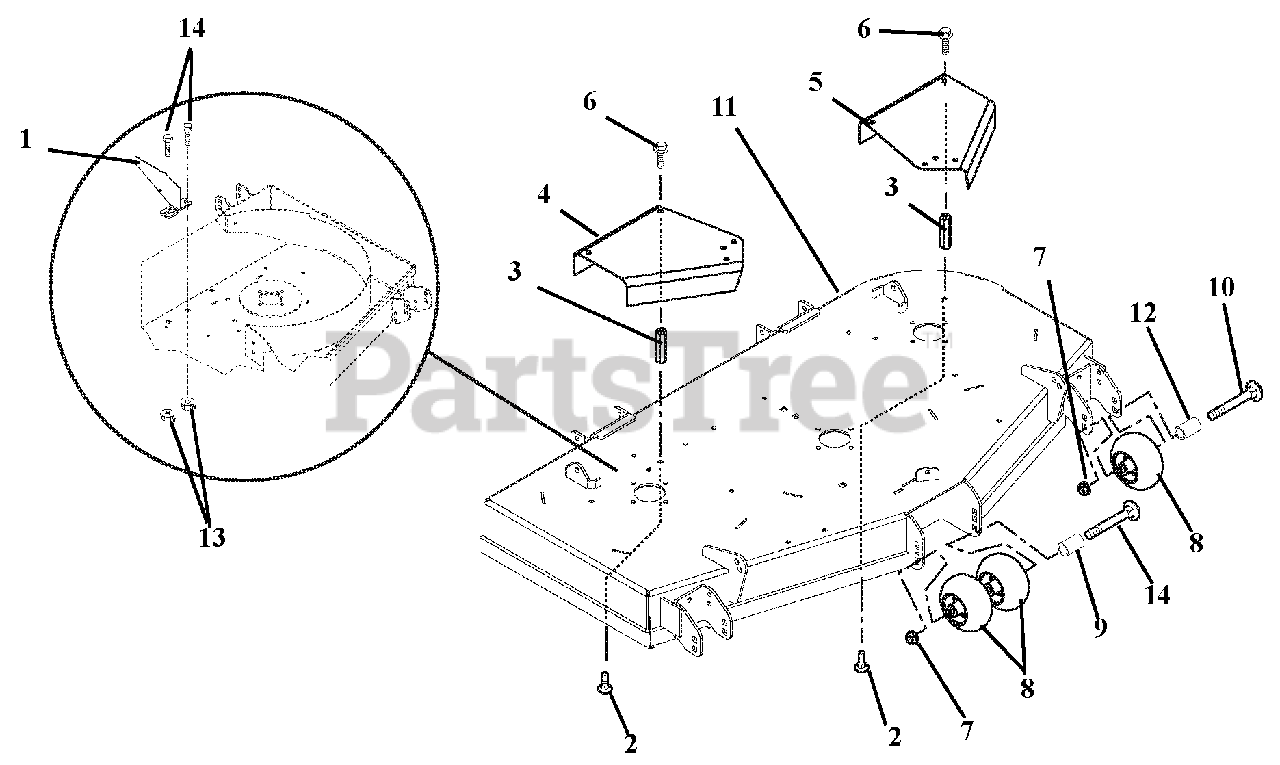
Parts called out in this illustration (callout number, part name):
1	Rear Deflector Baffle
2	Bolt, Round Head Square Neck .31-18 x .75 Loctite with Epoxy Patch
3	Nut, Coupling .31-18 x 3.00
4	52-in. Right Hand Spindle Guard (992322)
5	52-in. Left Hand Spindle Guard(992322)
6	Bolt, SEMS .31-18 x .62
7	Nut .50-13 Nyloc Flange
8	Anti-Scalp Wheel
10	Bolt-Round Head Square Neck .50-13 x 5.00
11	52-in. Mower Deck (992322)
12	Spacer, .510 x .625 x 3.35
13	Nut, .38-16 Nyloc Flange
14	Bolt, Round Head Square Neck, 3/8-16 x 1.00
